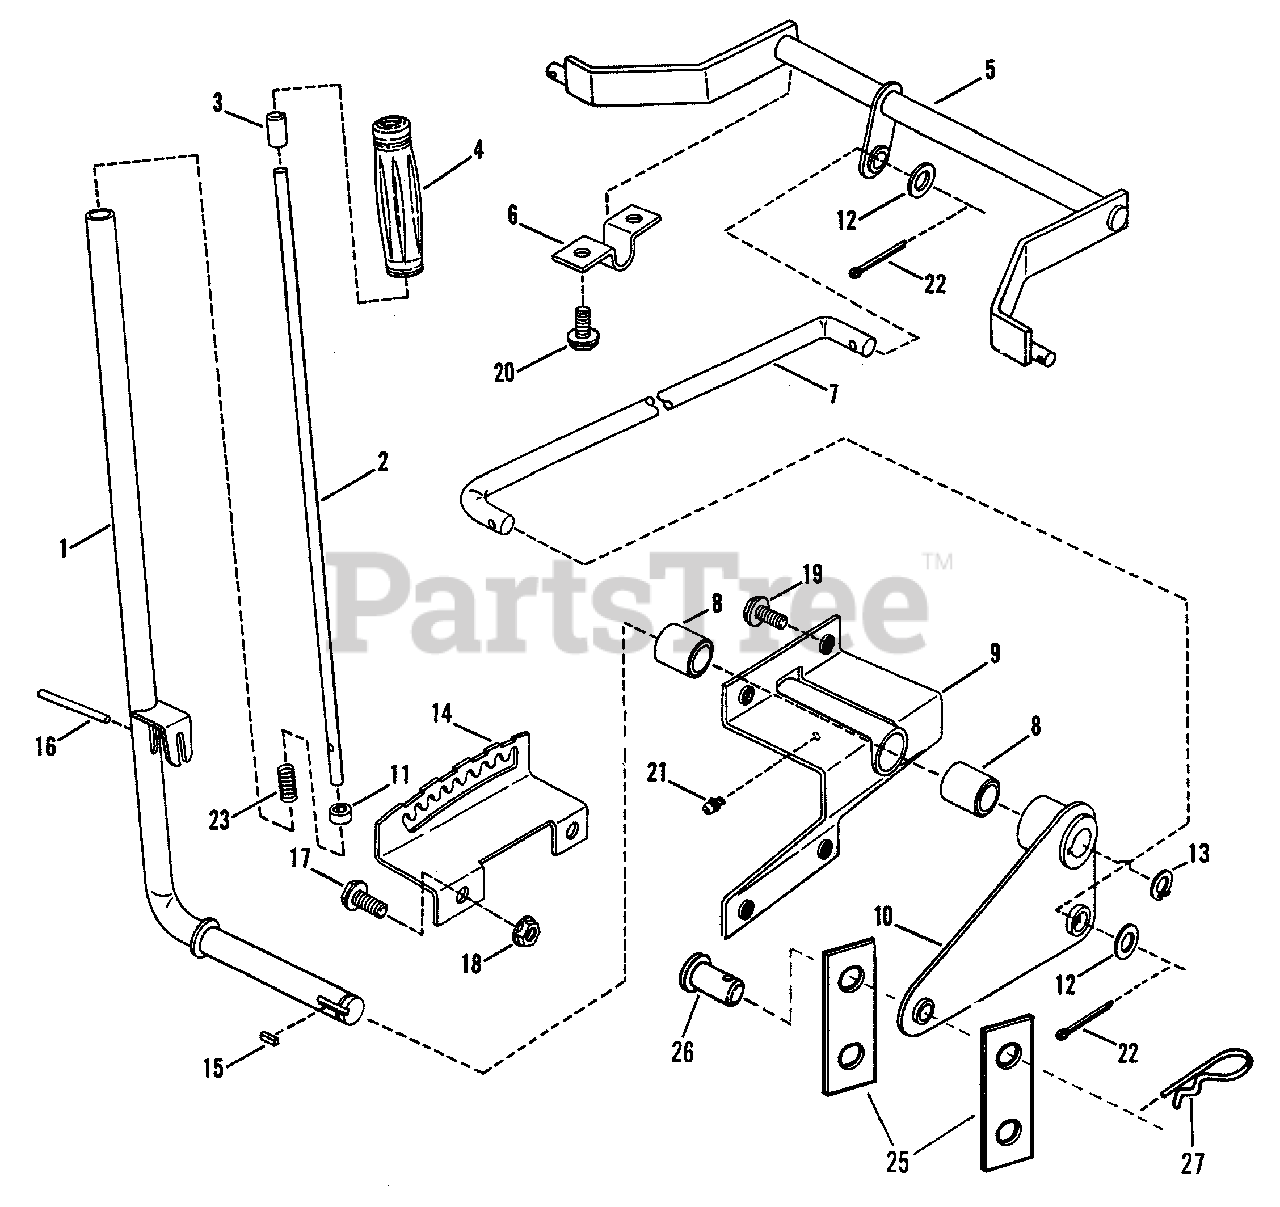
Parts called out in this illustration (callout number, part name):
1	ARM, Implement Lift Lever
2	ROD, Lift Lever
3	CAP, Lift Release
4	GRIP, Handle
5	ARM, Rear Lift
6	BRACKET, Hanger
7	LIFT-ROD
8	BEARING, Sleeve
9	PIVOT ASSY, Lift Lever
10	LEVER-ARM
11	PLUG, Rod
12	WASHER, 1/2 SAE
13	RING, 7/8" Ext. Retaining
14	QUADRANT, Lift Lever
15	KEY, 1/4 x 1/4 Square
16	PIN, 3/16 x 2" Groove
17	BOLT, 3/8-16 x 3/4" Hex Flange Lock
18	NUT, 3/8-16 Hex Flange Lock
19	SCREW, 5/16-18 x 5/8" Hex Washer Face Self-Tap
20	SCREW, 3/8-16 x 1/2" Hex Washer Face Self-Tap
21	LUBE FITTING, Straight (press-fit for .187 dia. Hole)
22	PIN, 1/8 x 1" Cotter
23	SPRING, Lift Handle
25	LINK, Deck Hanger
26	PIN, 3/8 x 1 1/16" Clevis
27	PIN, 1.6 Hair
